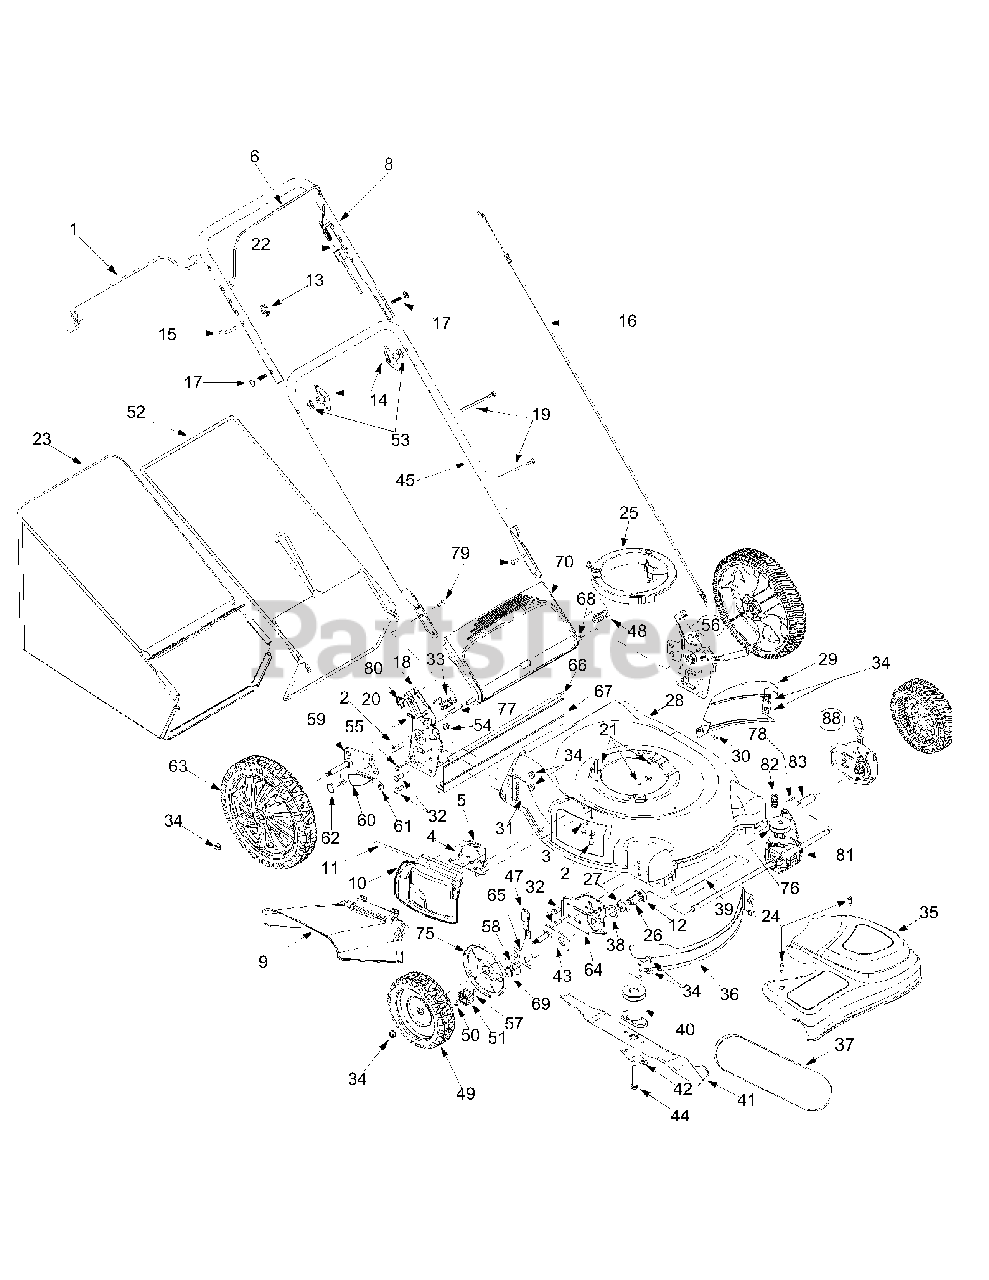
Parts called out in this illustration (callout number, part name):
1	Drive Bail Handle
2	TT Screw 1/4-20 x 0.5
3	Bell Washer.265 x 0.75
4	Deflector Chute Adapter
5	Torsion Spring
6	Operator Bail: Blade Control Handle
9	Chute Deflector
10	Mulch Plug Complete
11	Hinge Pin
12	Bearing Retainer
13	Handle Knob
14	Handle Knob
15	Eye Bolt
16	Control Cable - 39"
17	Carriage Bolt 5/16-18 x 2.0
18	RH Handle Bracket
18	LH Handle Bracket
19	Cable Tie
20	Cotter Pin
21	Self-Tapping Sems Screw
22	Drive Cable - 50.50"
23	Grassbag Assembly
24	Shoulder Screw # 12 -24
25	Engine Spacer
26	Bearing Sleeve
27	Bearing Support
28	21" Deck
29	LH Rear Baffle
30	Screw AB: 1/4-14:.625
31	RH Rear Baffle
32	Hex Screw 3/8-16 x.75
33	Torsion Spring RH
34	Flange Lock Nut 3/8-16
35	Transmission Cover
36	Front Baffle
37	V-Belt
38	Wave Washer
39	Sleeve Spacer 9.04" Lg.
40	Blade Adapter w/ Pulley
41	21" Mulching Blade
42	Blade Bell Support
43	Pivot Plate Assembly
44	Hex Screw 3/8-24 x 2.50
45	Lower Handle
47	Adjustment Knob
48	Torsion Spring LH
49	Wheel 8"
50	Snap Ring
51	Gear 14T RH FWD
51	Gear 14T LH FWD
52	Grass Bag Frame
53	Saddle Washer
54	Hex Flange Lock Nut 3/8-16
55	TT Scr. w/Washer 1/4-20 x.625
56	RH Handle Bracket Assembly
56	LH Handle Bracket Assembly
57	Dowel Pin
58	Washer
59	Pivot Arm Assembly - RH
59	Pivot Arm Assembly - LH
60	Rear Spring Lever
61	Foam Grip
62	Shoulder Scr.500 Dia. x.434
63	Wheel: 12"
64	Height Adjuster Plate - RH
64	Height Adjuster Plate - LH
65	Front Lever - RH
65	Front Lever - LH
66	Wire
67	Rear Trailing Shield
68	Pivot Rod
69	Snap Ring
70	Rear Discharge Door
75	Wheel Dust Cap
76	Input Pulley
77	Spacer .375 x.50 x 1.02" Lg.
78	Roll Pin
79	Carriage Bolt 1/4-20
80	Wing Nut
81	Transmission Assembly
82	Belt Tension Spring
83	Slev. Spacer 2.1" Lg.
88	Height Adjustment Assembly LH
88	Height Adjustment Assembly RH
